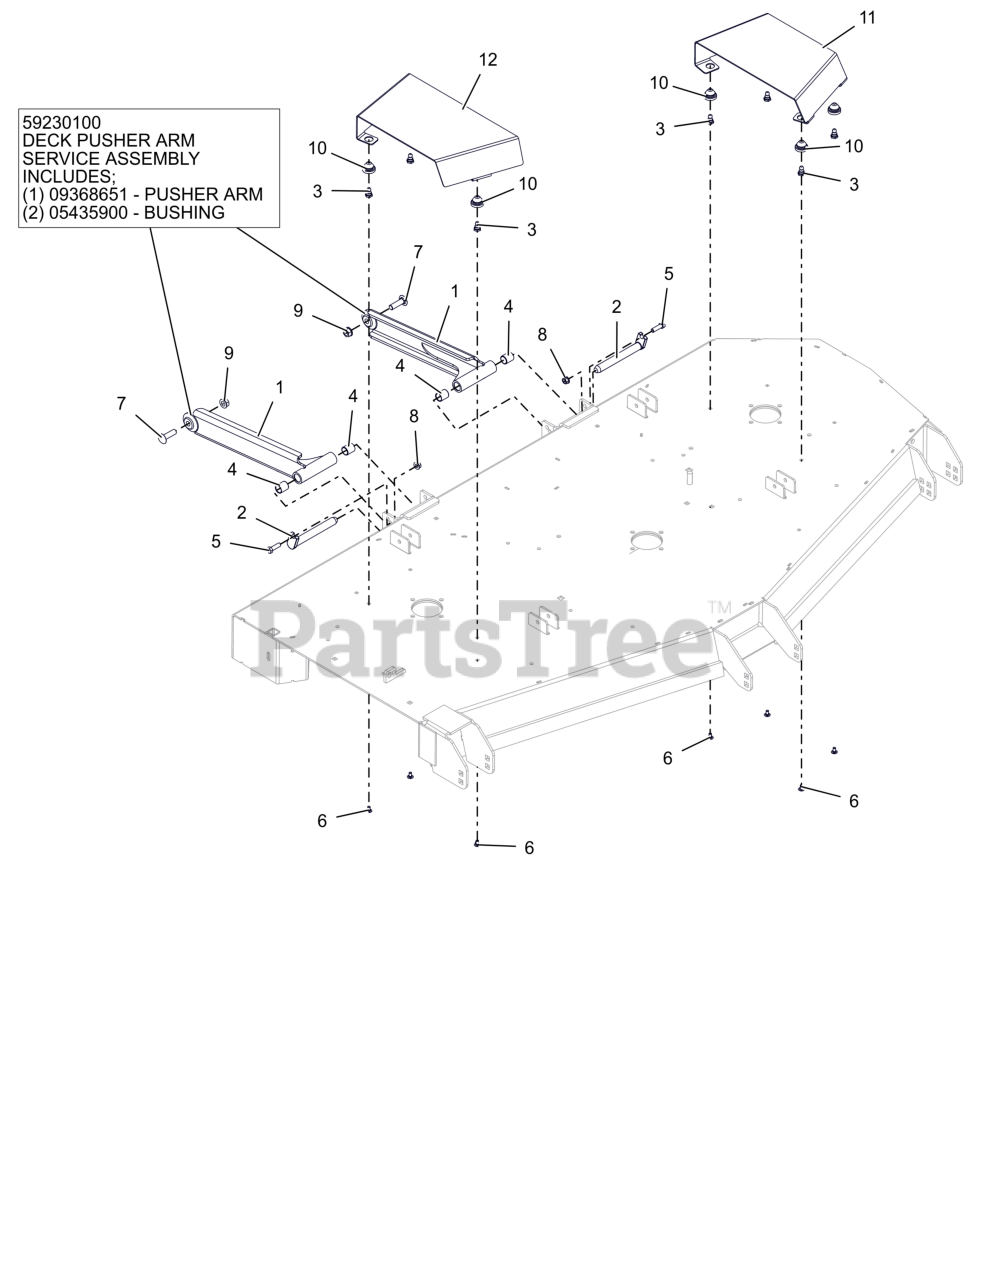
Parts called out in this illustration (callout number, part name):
1	WLDMT, DECK STABILIZER ARM (BLACK)
1	DECK PUSHER ARM SERVICE ASSEMBLY
2	PIN, MOWER MTG
3	STUD, BALL FEMALE .250-20 THREAD
4	BRG, .750 X .875 X 1.000
5	BLT, HEX .38-16X1.25 G5 ZCC
6	BLT, RHSSN.25-20X.500 G5 ZCC
7	BTL,RHSSN .500-13 X 1.75 G5 ZCC
8	NUT-LK-CTR-FLG .375-16 GF ZCC
9	NUT-LK-CTR-FLG .500-13 GG ZCC
10	COUPLING, RUBBER PUSH-IN
11	GUARD, LH DECK BELT 72" (RED)
12	GUARD, RH DECK BELT 72" (RED)
